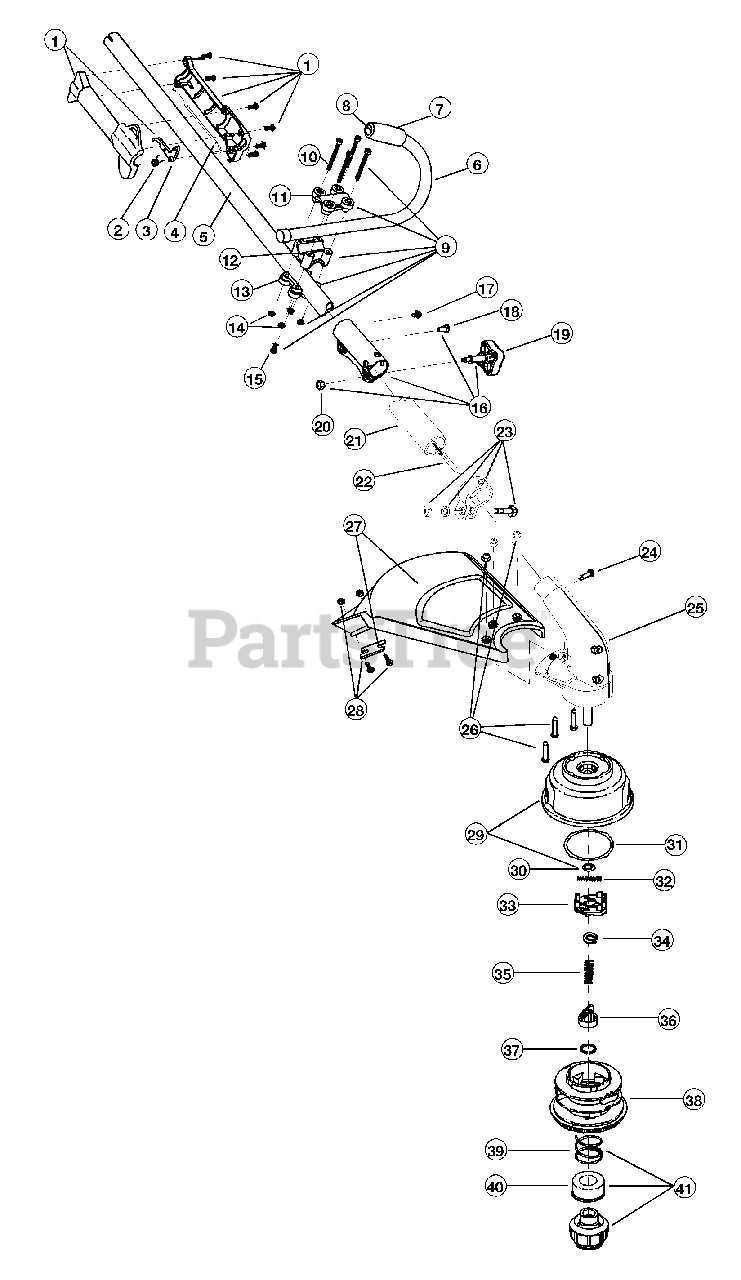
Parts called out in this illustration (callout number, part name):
1	Throttle Housing Assembly
2	Throttle Trigger Spring
3	Throttle Trigger
4	Throttle Cable
5	Upper Drive Shaft Housing Assembly
6	J-Handle Assembly
8	Tube Closure
9	Handle Bracket Assembly
11	Upper Handle Clamp
12	Middle Handle Clamp
13	Lower Handle Clamp
15	Anti-Rotation Screw
16	Click-Link Coupler
19	Adjustment Knob
20	Knob Retaining Nut
21	Lower Drive Shaft Housing Assembly
22	Lower Flexible Drive Shaft
23	Lower Clamp Assembly
24	Anti-Rotation Screw
25	Gearbox Assembly
26	Shield Mounting Hardware
27	Shield and Blade Assembly
28	Blade Assembly
29	Outer Spool Assembly
30	Retainer
31	Thrust Washer
32	Small Spring
33	Slider
36	Plunger
38	Inner Reel
39	Large Spring
40	Foam Seal
41	Bump Knob Assembly
